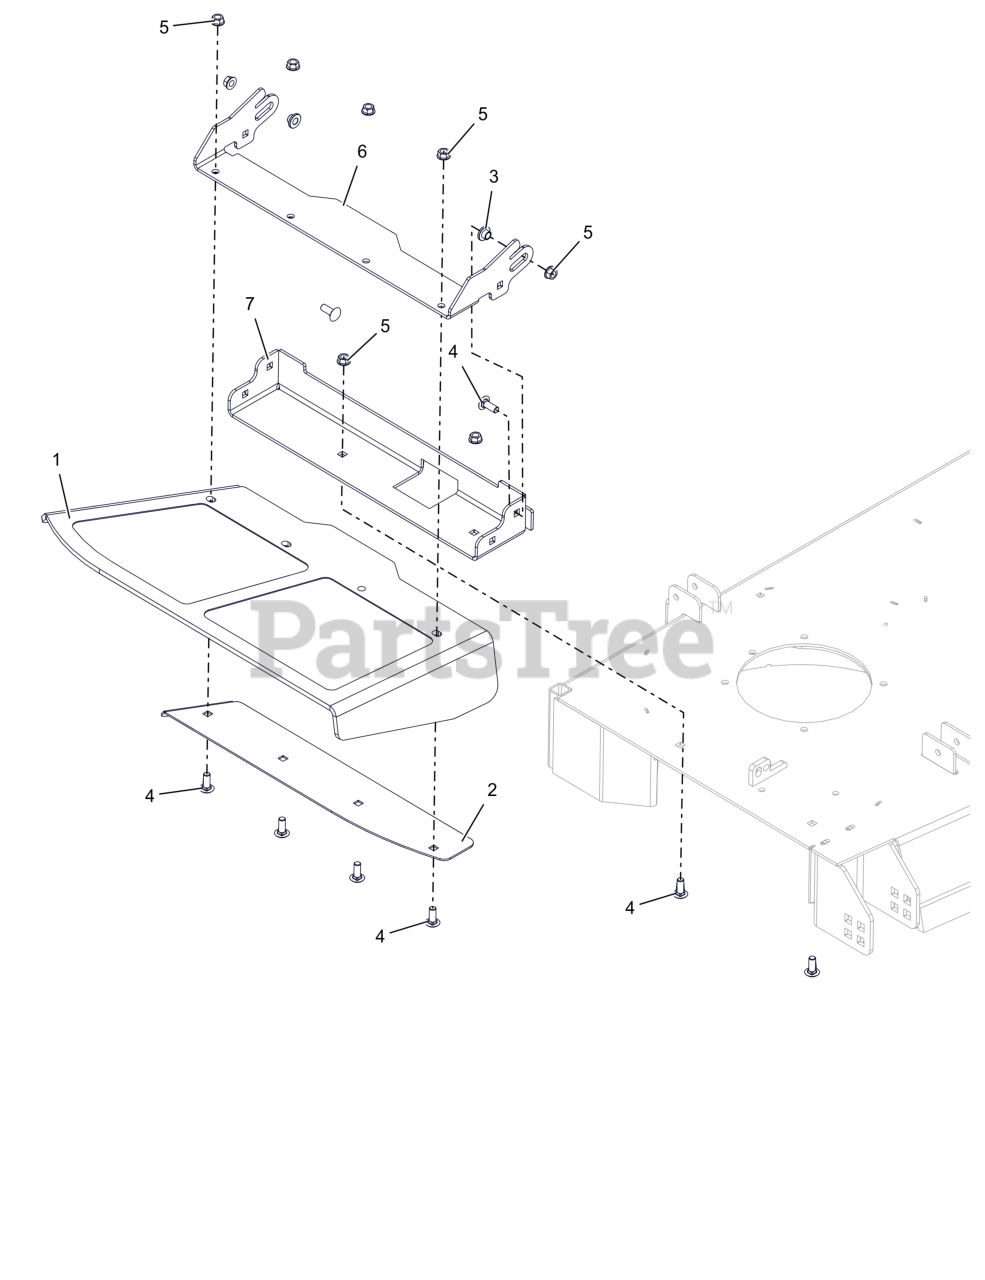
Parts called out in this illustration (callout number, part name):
1	CHUTE, FORMED RUBBER DISCHARGE-EXT
2	72" DISCH CHUTE CLAMP PLT -RED
3	BSHG-FLG .385X.500X.875X.406
4	BLT,RHSSN .38-16X1.00 G5 ZCC
5	NUT-LK-CTR-FLG .375-16 GF ZCC
6	BRKT, CHUTE MTG (RED)
7	BASE, DISCHARGE CHUTE MTG (RED) W/ SAFETY DECALS
